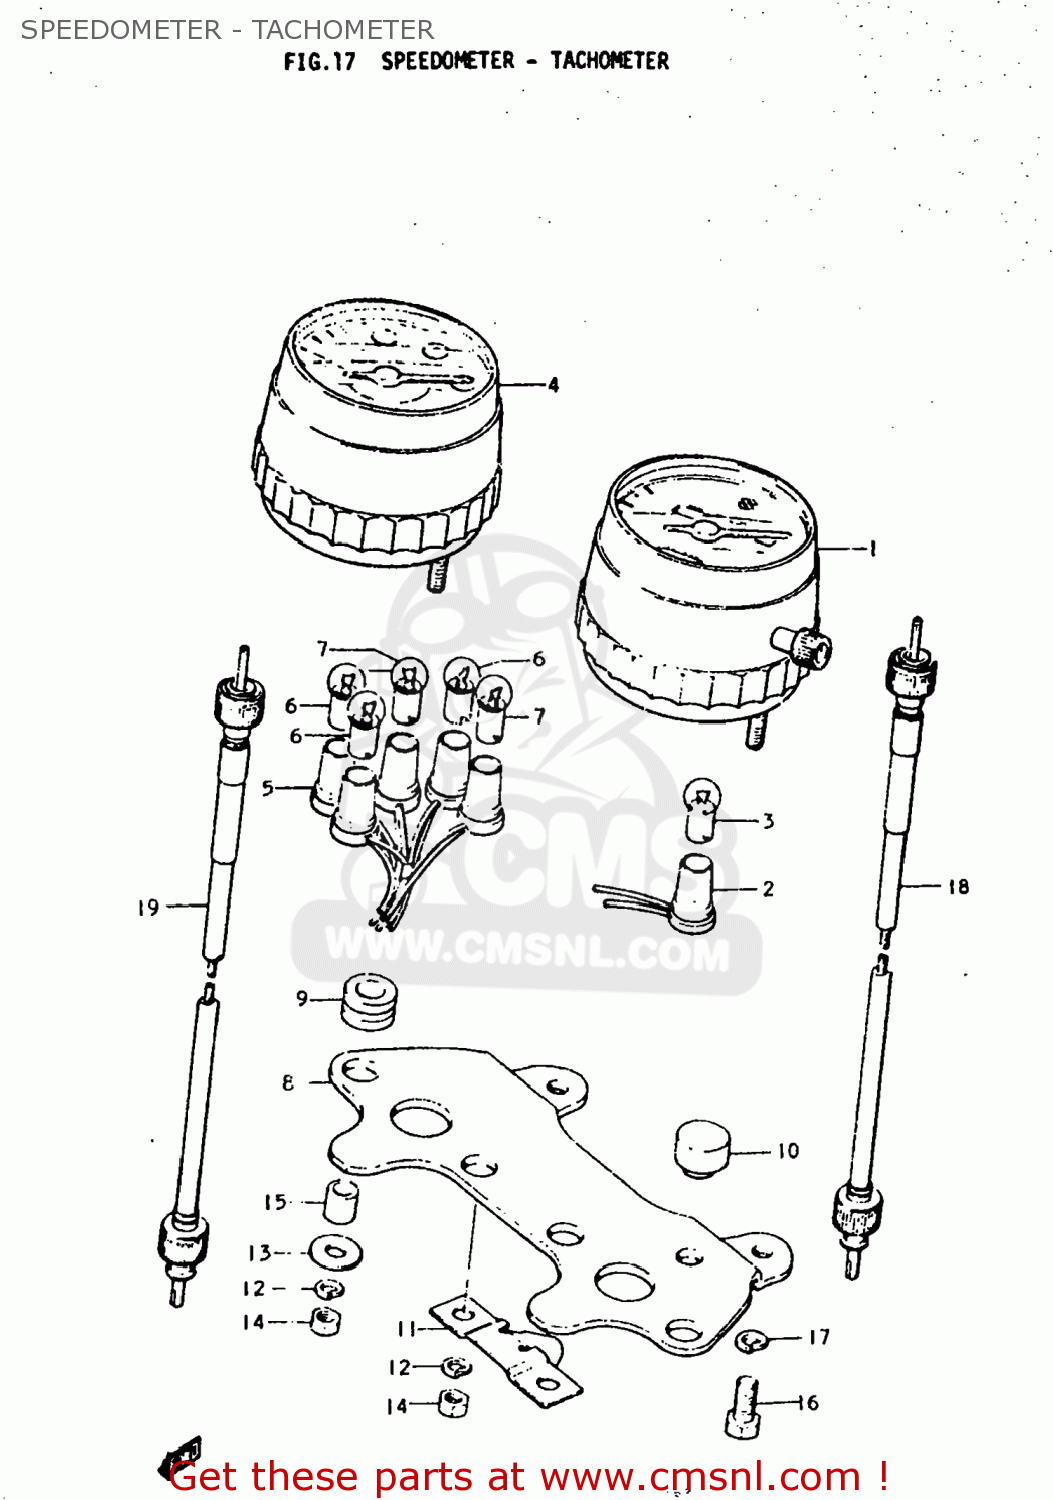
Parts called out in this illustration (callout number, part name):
0	SPEEDOMETER ASSEMBLY
1	SPEEDOMETER ASSEMBLY
2	SOCKET,METER
3	BULB(12V3.4W,STANLEY,A72A)
4	METER,TACHOMETER
5	SOCKET,TACHOMETER
6	BULB(12V3.4W,STANLEY,A72A)
7	BULB(12V1.7W,A71A)
8	BRACKET,METER
9	CUSHION
10	CUSHION,METER
11	COVER,METER,UNDER
12	LOCK WASHER
13	WASHER (5.5X16X1.2)
14	NUT
15	SPACER,METER NO.2
16	BOLT
17	LOCK WASHER
18	CABLE ASSEMBLY,SPEEDOMETER
19	CABLE ASSEMBLY,TACHOMETER
